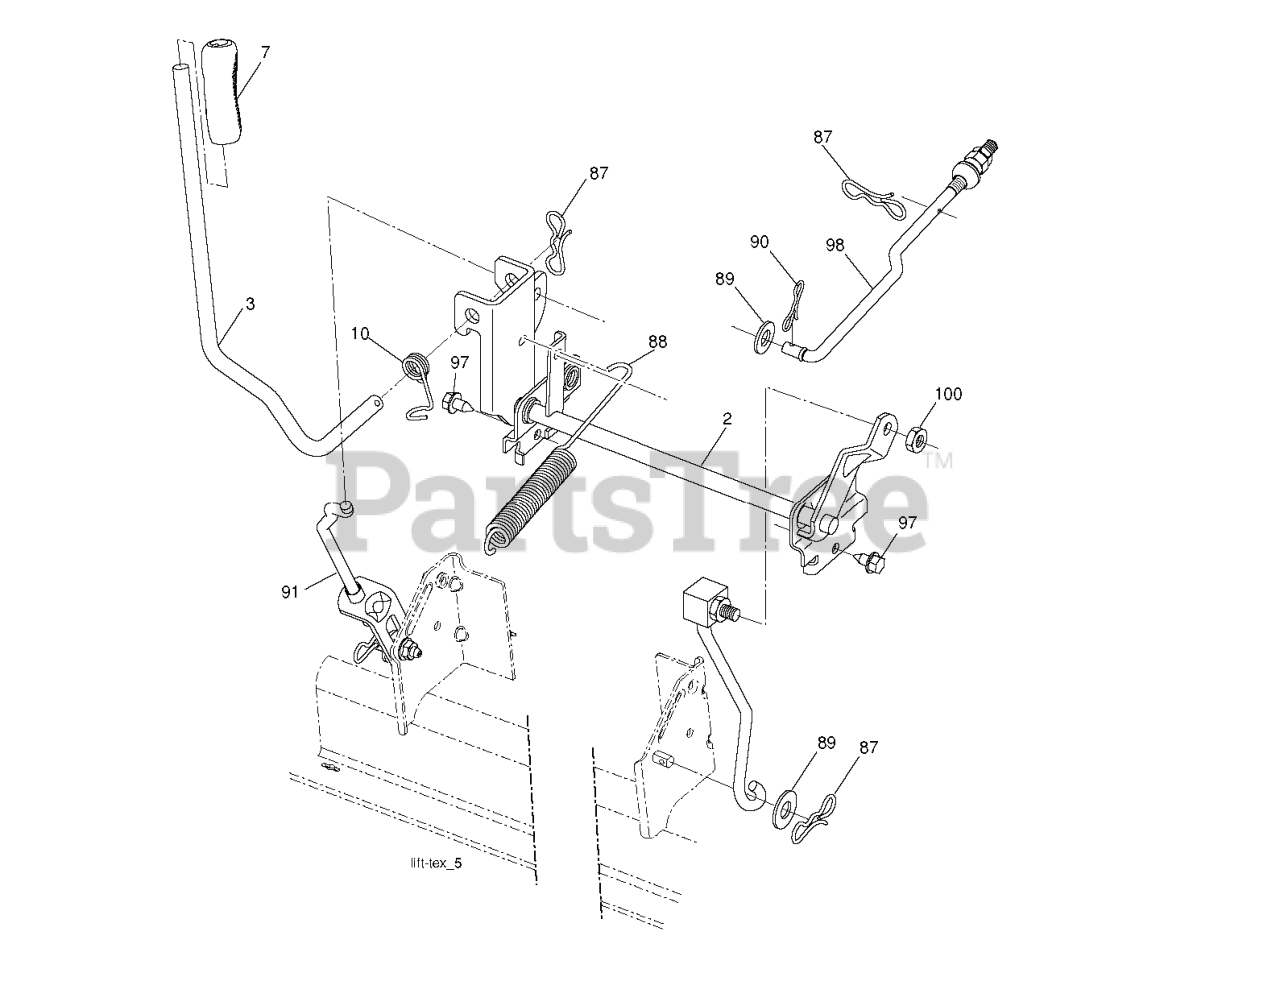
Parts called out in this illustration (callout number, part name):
2	SHAFT.ASM.LIFT.CROSS.H
3	LEVER.LIFT.HANDLE.GT
7	GRIP.LEVER.5625.ID
10	SPRING.TORSION.LIFT.HANDLE
87	PIN.COTTER.7/16.BOW TI.
88	SPRING.LIFT.ASSIST.GT2
89	WASHER.CLEAR.ZINC
90	PIN.COTTER.5/16.BOW TI
91	LINK.ASM.LIFT.REAR
97	SCREW 3/8-16X3/4
98	LINK.ASM.SUSP.FRONT.MW
100	LOCKNUT
